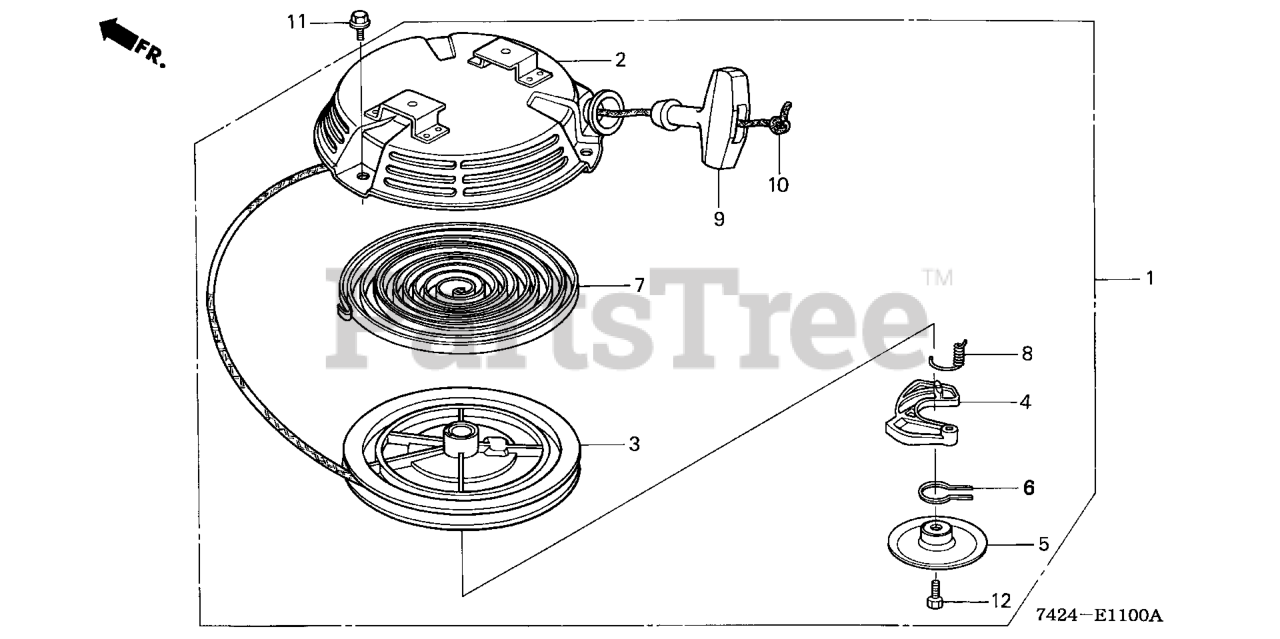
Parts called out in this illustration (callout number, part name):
1	STARTER ASSY., RECOIL *R280* (POWER RED)
2	CASE, RECOIL STARTER *R280* (POWER RED)
3	PULLEY, RECOIL STARTER
4	RATCHET, STARTER
5	PLATE, FRICTION
6	SPRING, FRICTION
7	SPRING, RECOIL STARTER
8	SPRING, RETURN
9	KNOB, STARTER
10	ROPE, RECOIL STARTER (#4X55")
10	ROPE, LONG (55")
11	BOLT, FLANGE (6X8)
12	BOLT, HEX. (6X20)
